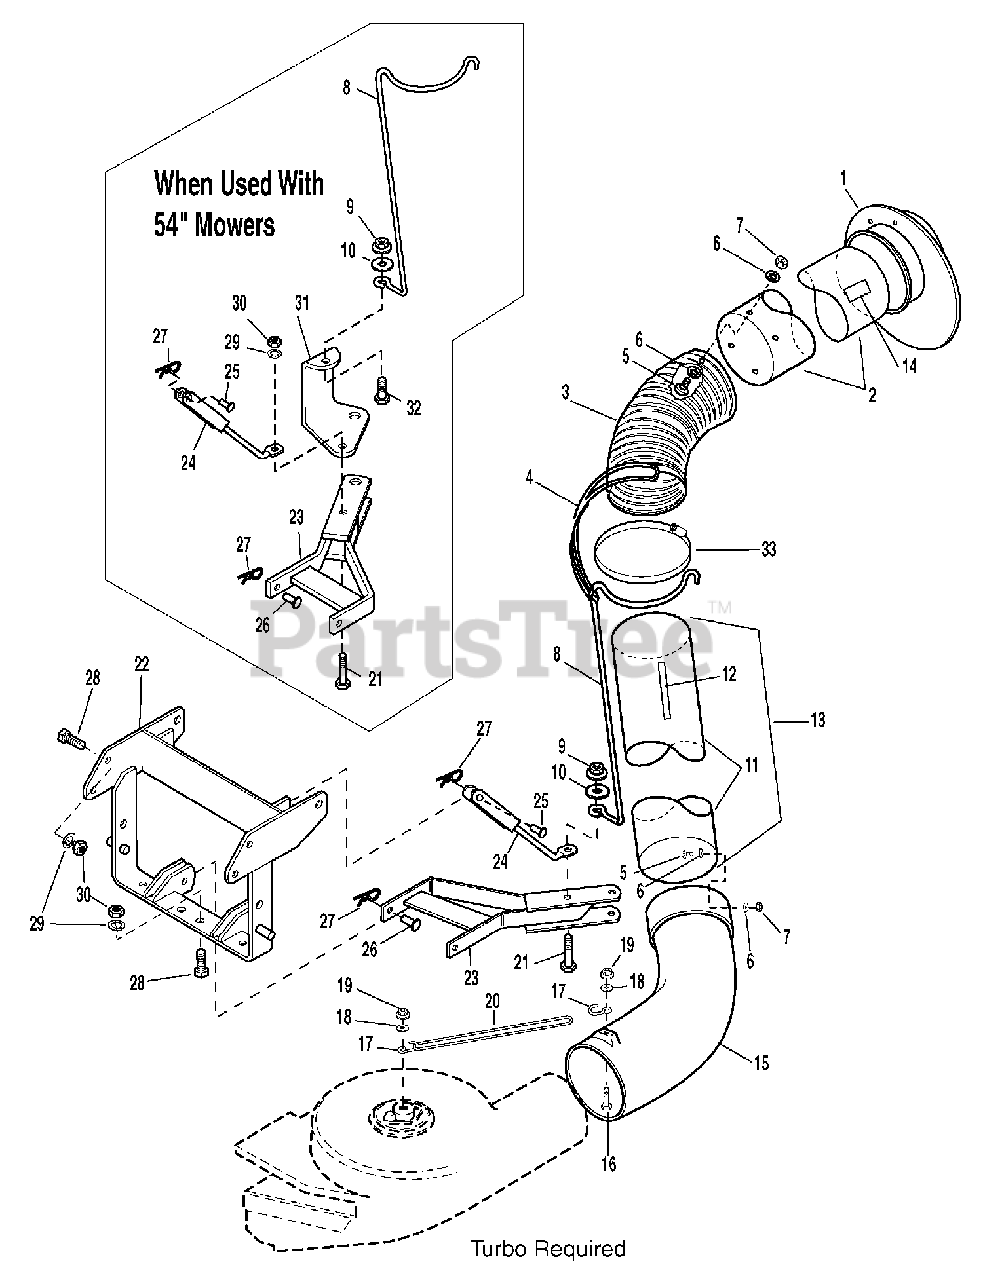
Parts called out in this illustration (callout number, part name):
1	CONNECTOR, Cart
2	TUBE, 51" w/ Cleaning Instructions
3	HOSE, Vac, Col, 6 X12
4	STRAP, Rubber
5	SCREW, Truss Head Phillips, 10-32 X 1/2
6	WASHER, Plain
7	NUT, Hex Washer Assembly, 10-32
8	SUPPORT, Rod
9	FLANGE, Locknut, 1/2-13
10	WASHER, 1/2 -13
12	DECAL, Cleaning Instructions
13	DECAL, Warning
14	TUBE & DECAL ASSEBLY (Incl Ref. 11-13)
16	CAPSCREW, Hex Head, 5/16-18 X 5/8
18	WASHER, 5/16
19	NUT, Hex Flange, 5/16-18
20	STRAP, Rubber
21	CAPSCREW, Hex Head, 1/2-13 X 3-1/2
22	HITCH, Assembly
23	DRAWBAR, Assembly
24	SUPPORT, Assembly
25	PIN, Round Head, 7/16 X 1-3/4
26	PIN, Yoke, Drilled
27	CLIP, Spring
28	CAPSCREW, Hex Head, 1/2-13 X 1-1/4
29	LOCKWASHER, Spring 1/2
30	NUT, Hex, 1/2-13
31	EXTENSION, Support
32	CAPSCREW, Hex Head, 1/2-13 X 1-3/4
33	CLAMP, Band, 6"
